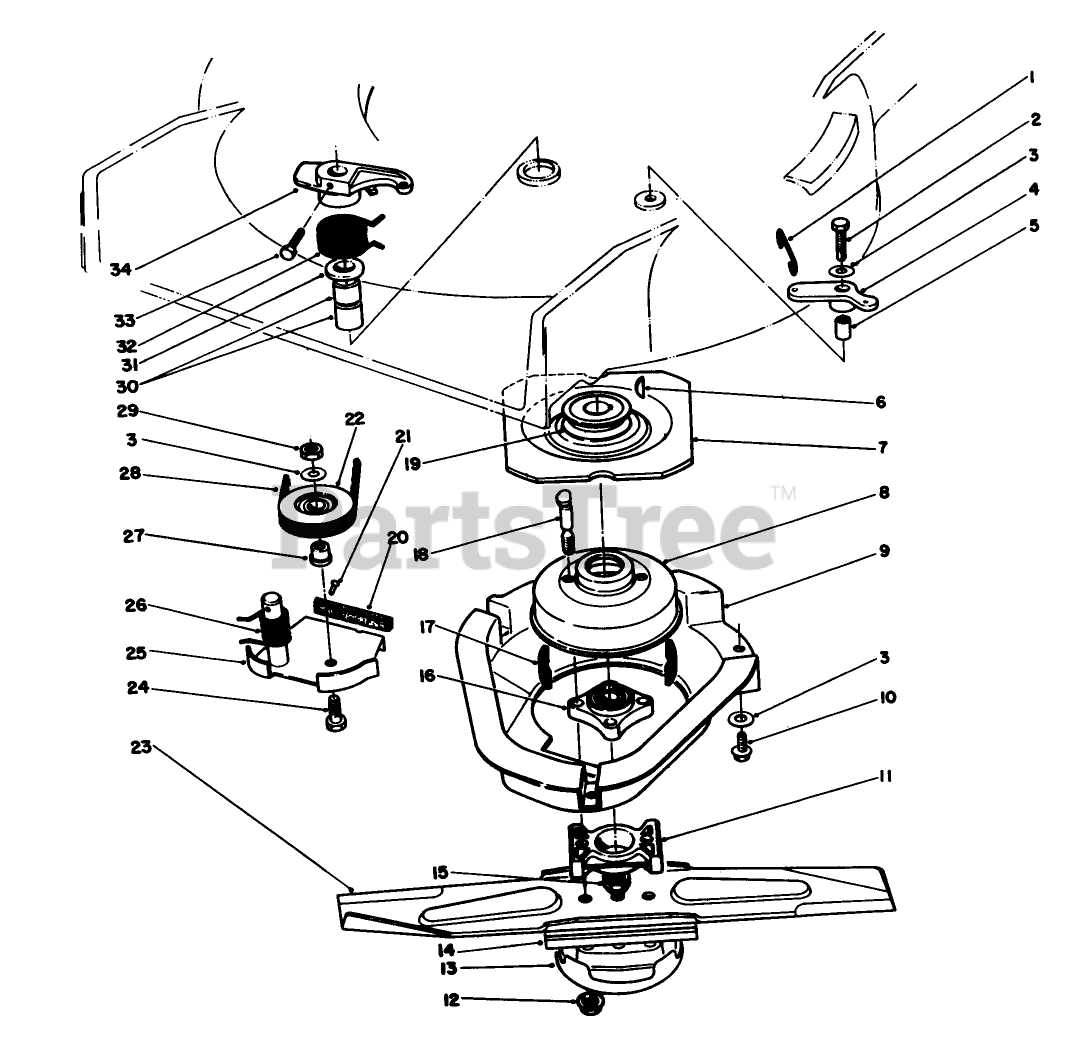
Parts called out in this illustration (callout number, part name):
1	LINK-CONTROL
2	SCREW-HH
3	WASHER-PLAIN
4	BELLCRANK
5	SLEEVE-BELLCRANK
6	KEY-WOODRUFF
9	SHIELD BBC
10	SCREW-HWHTF
12	NUT-LOCK
13	CUP-SCALP, ANTI
15	NUT-LOCK, NI
16	HUB ASM
17	DAMPENER-VIBRATION
18	BOLT-BLADE
19	PULLEY
20	Pad-Brake
21	.185 DIA X .375 RT +
24	SCREW-HH
26	SPRING-TORSION
27	HUB-PULLEY, IDLER
28	V-BELT
29	NUT-LOCK, NI
30	BEARING
31	WASHER
32	SPRING-TORSION
33	SCREW-HH
34	LEVER
